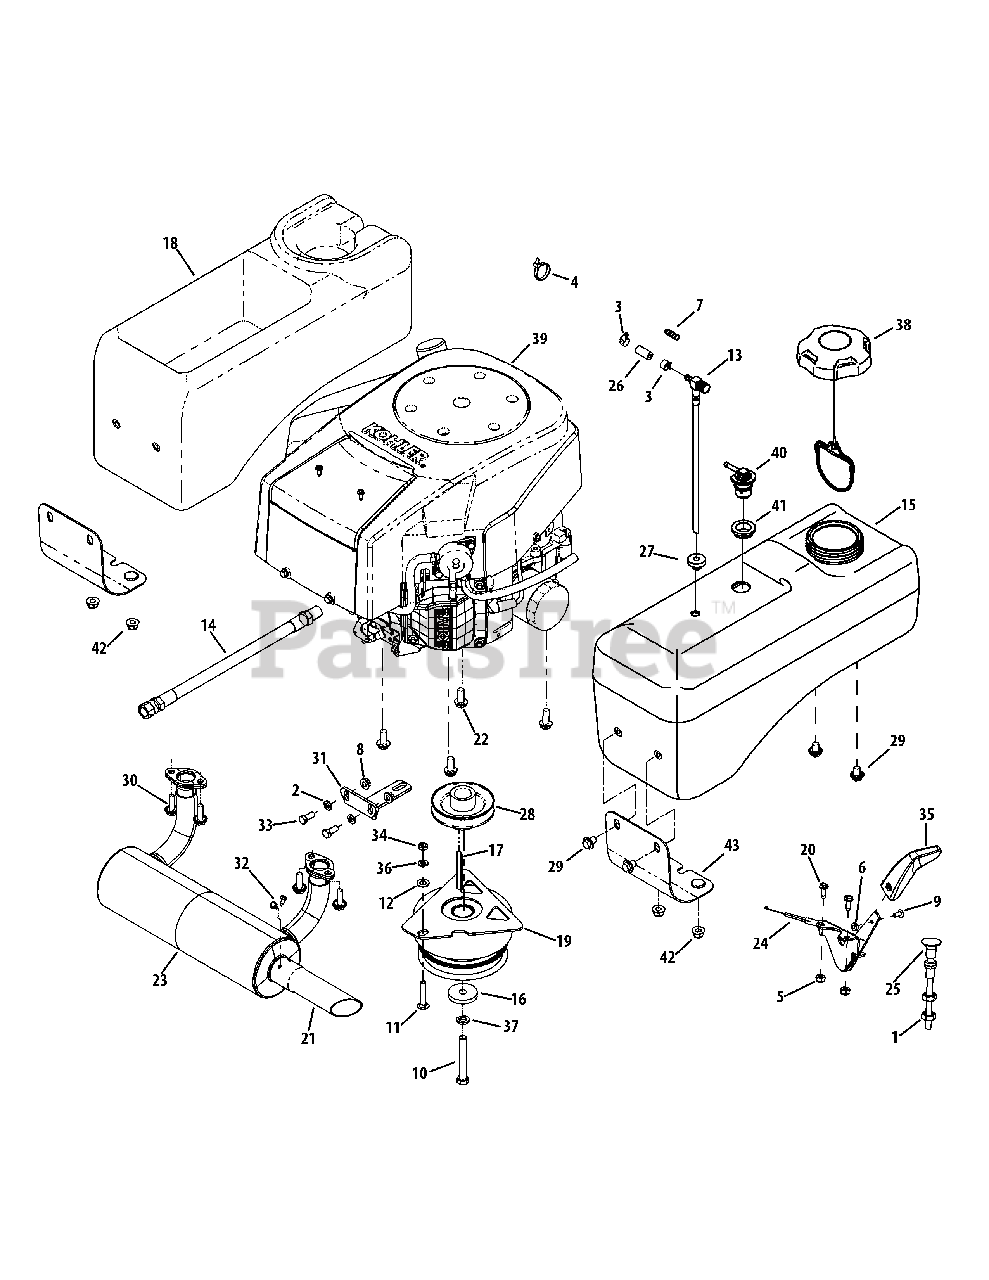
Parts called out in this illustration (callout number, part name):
1	Jam Nut, 3/8-24
2	Washer, .344 x .688 x .063
3	Hose Clamp, .490
4	Cable Tie
5	Nylock Nut, #10-32
6	Nut, #8-32
7	Hose Vent, 3/16 EPA
8	Flange Counterlock Nut, 5/16-18
9	Machine Screw, #8-32 x .356
10	Hex Screw, 7/16-20 x 3.00
11	Carriage Bolt, 5/16-18 x 1.75
12	Washer, .406 x .750 x .063
13	Fuel Pick-Up Fitting
14	Oil Drain Hose
15	Fuel Tank Assembly
16	Washer, .438 x 1.745 x .250
17	Bevel Key, .250 x .250 x 2.75
18	Utility Bin
19	PTO
20	Flange Screw, #10-32 x .500
21	Straight Exhaust Pipe
22	Flange Screw, 3/8-16 x .875
23	Muffler
24	Throttle Control Cable
25	Choke Cable
26	Fuel Hose, 1/4
27	Fuel Tank Grommet
28	Transmission Drive Pulley
29	Hex Flange Screw, M10-1.5 x 5.0 8.8
30	Hex Flange Screw, 5/16-18 x 1.0
32	Hex Washer Screw, #10-16 x 0.500
33	Hex Screw, 5/16-18 x .75
34	Jam Nut, 5/16-18
35	Throttle Control Knob
36	Lock Washer, 5/16
37	Lock Washer, 7/16
39	Kohler SV715-3025 Engine
39	Kohler SV725-3020 Engine
40	Rollover Valve
41	Rubber Grommet, 23 x 3.55
42	Nut, Flange Lock, 3/8-16, Grf,
43	Fuel Tank Bracket
